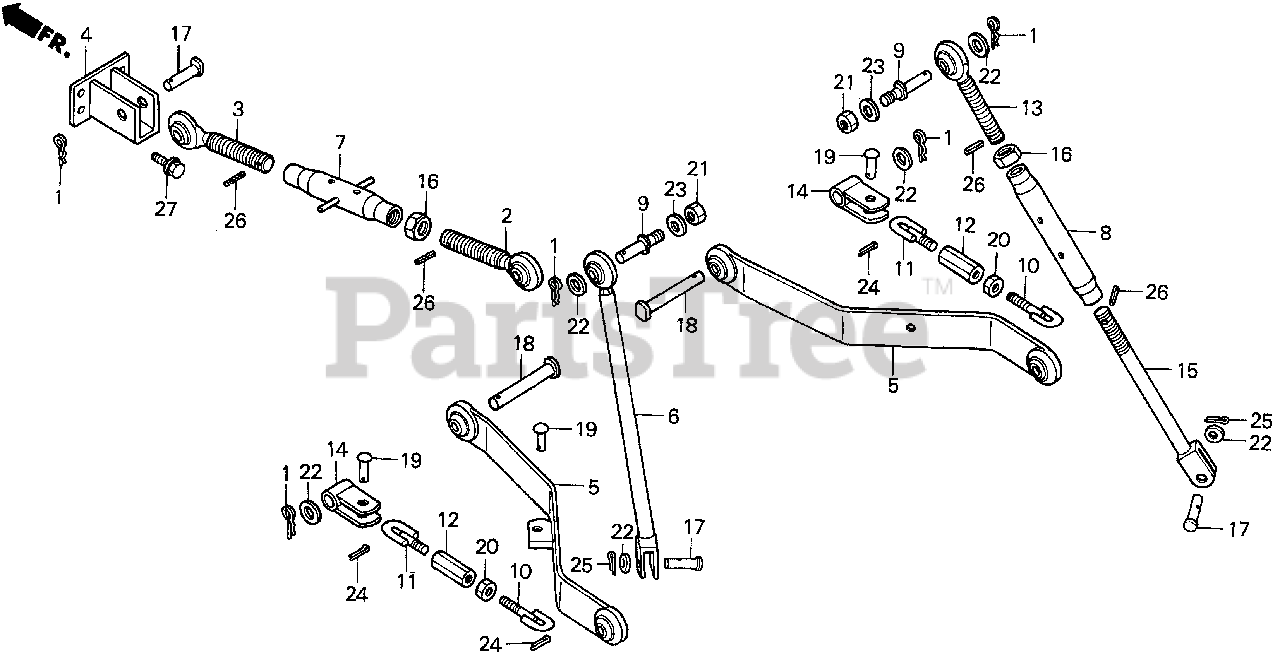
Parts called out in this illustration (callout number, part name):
2	HOLDER, R. LINK (UPPER)
3	HOLDER, L. LINK (UPPER)
4	BRACKET, LINK (UPPER)
5	LINK (LOWER)
6	ROD, LIFT (LH)
7	BUCKLE, LINK TURN (UPPER)
8	BUCKLE, LIFT ROD TURN
9	PIN, LIFT ROD
10	BOLT A, TURN BUCKLE
11	BOLT B, TURN BUCKLE
12	BUCKLE, TURN
13	ROD, R. LIFT (UPPER)
14	BRACKET, TURN BUCKLE
15	ROD, R. LIFT (LOWER)
16	NUT, HEX. (20MM)
17	PIN, LINK (UPPER)
18	PIN, LINK (LOWER)
19	PIN, TURN BUCKLE
20	NUT, HEX. (12MM) Use up to Frame SN 5002482.
20	NUT, HEX. (12MM) Use from Frame SN 5002483.
21	NUT, HEX. (16MM)
22	WASHER, PLAIN (16MM)
23	WASHER, SPRING (16MM)
24	PIN, SPLIT (3.0X18)
25	PIN, COTTER (4X25)
26	PIN, SPRING (4X20)
27	BOLT, FLANGE (8X20)
